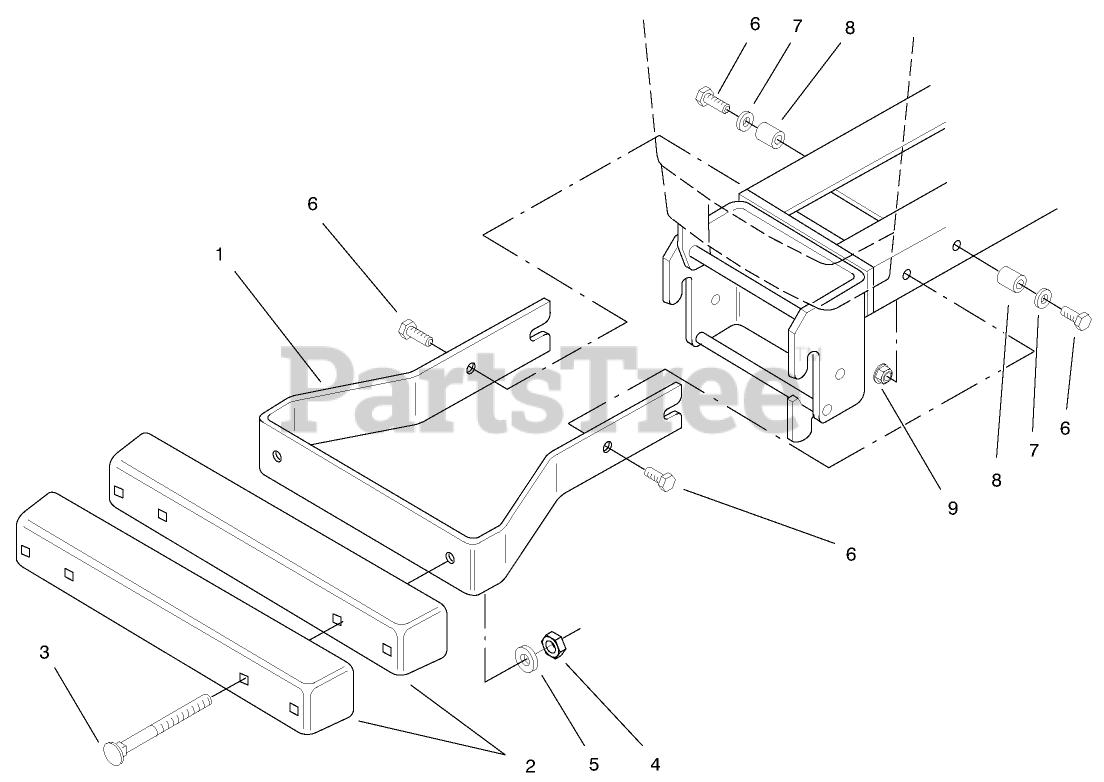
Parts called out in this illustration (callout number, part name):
1	FRAME-WEIGHT R
2	FRONT WEIGHT B
3	Bolt-Carriage
4	Nut
5	WASHER
6	Bolt
7	Washer
8	SPACER
9	NUT-FLANGE
